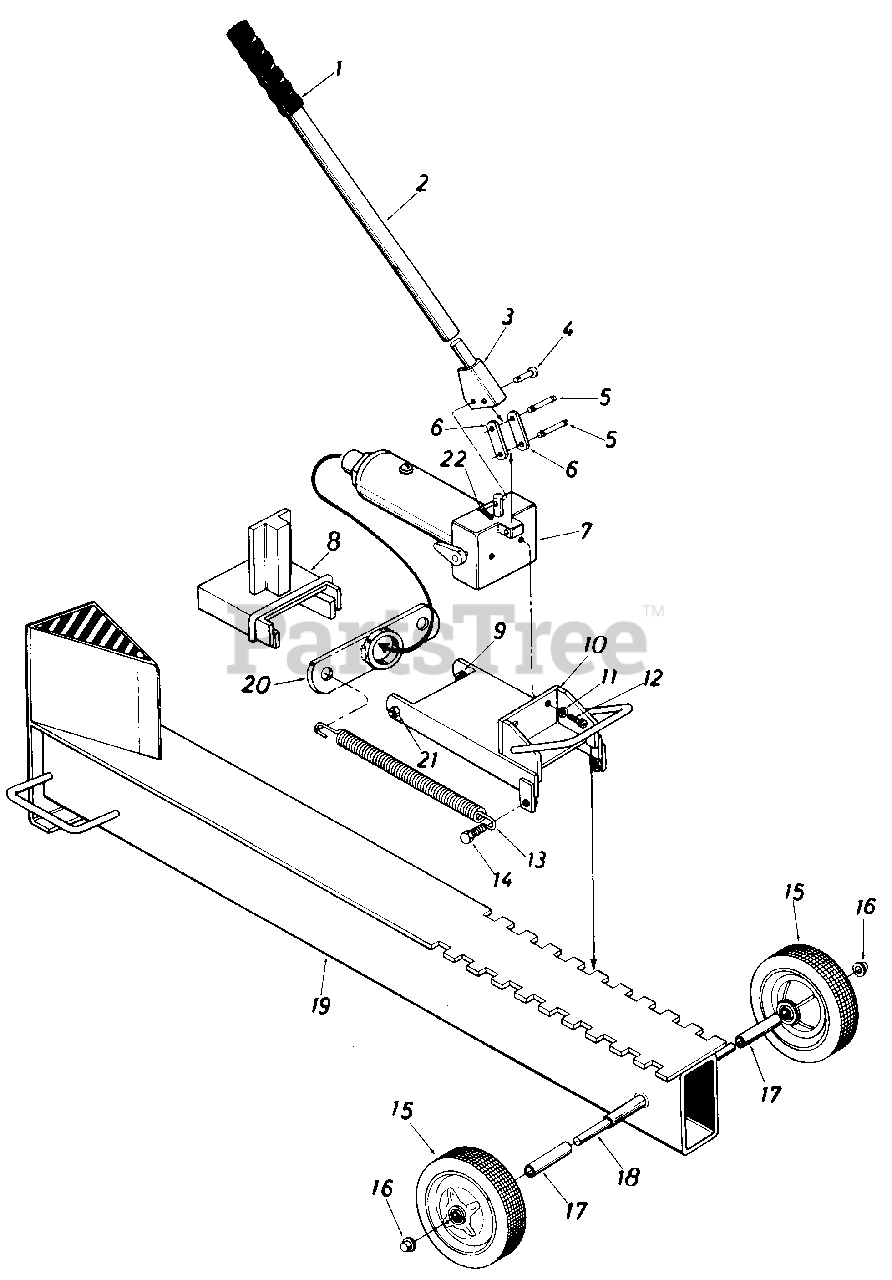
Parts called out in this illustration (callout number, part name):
1	Handle Grip
2	Handle 3/8" Dia. Rod
3	Handle Socket
4	Clevis Pin
5	Pin & Ring Assembly
7	Hydraulic Pump & Cylinder
8	Push Plate Ass'y.
9	Socket Hd. Bolt 1/2- 13 x .75" Lg.
10	Cylinder Mounting
11	L.-Wash. 3/8" I.D.*
12	Socket Hd. Bolt 3/8- 16 x .75" Lg.
13	Extension Spring .75" O.D. x 10.75" Lg.
14	Hex L.-Bolt 3/8-16 x .75" Lg.
15	Wheel 7.0" x 1.75"
16	1/2" Push Cap
17	Spacer
18	Axle 1/2" Dia. x 12"
19	Tube and Rail Ass'y.
20	Cyl. Return Ass'y.
21	Hex Cent. L.-Nut 1/2- 1 3 Thd.
22	Hair Pin Cotter
